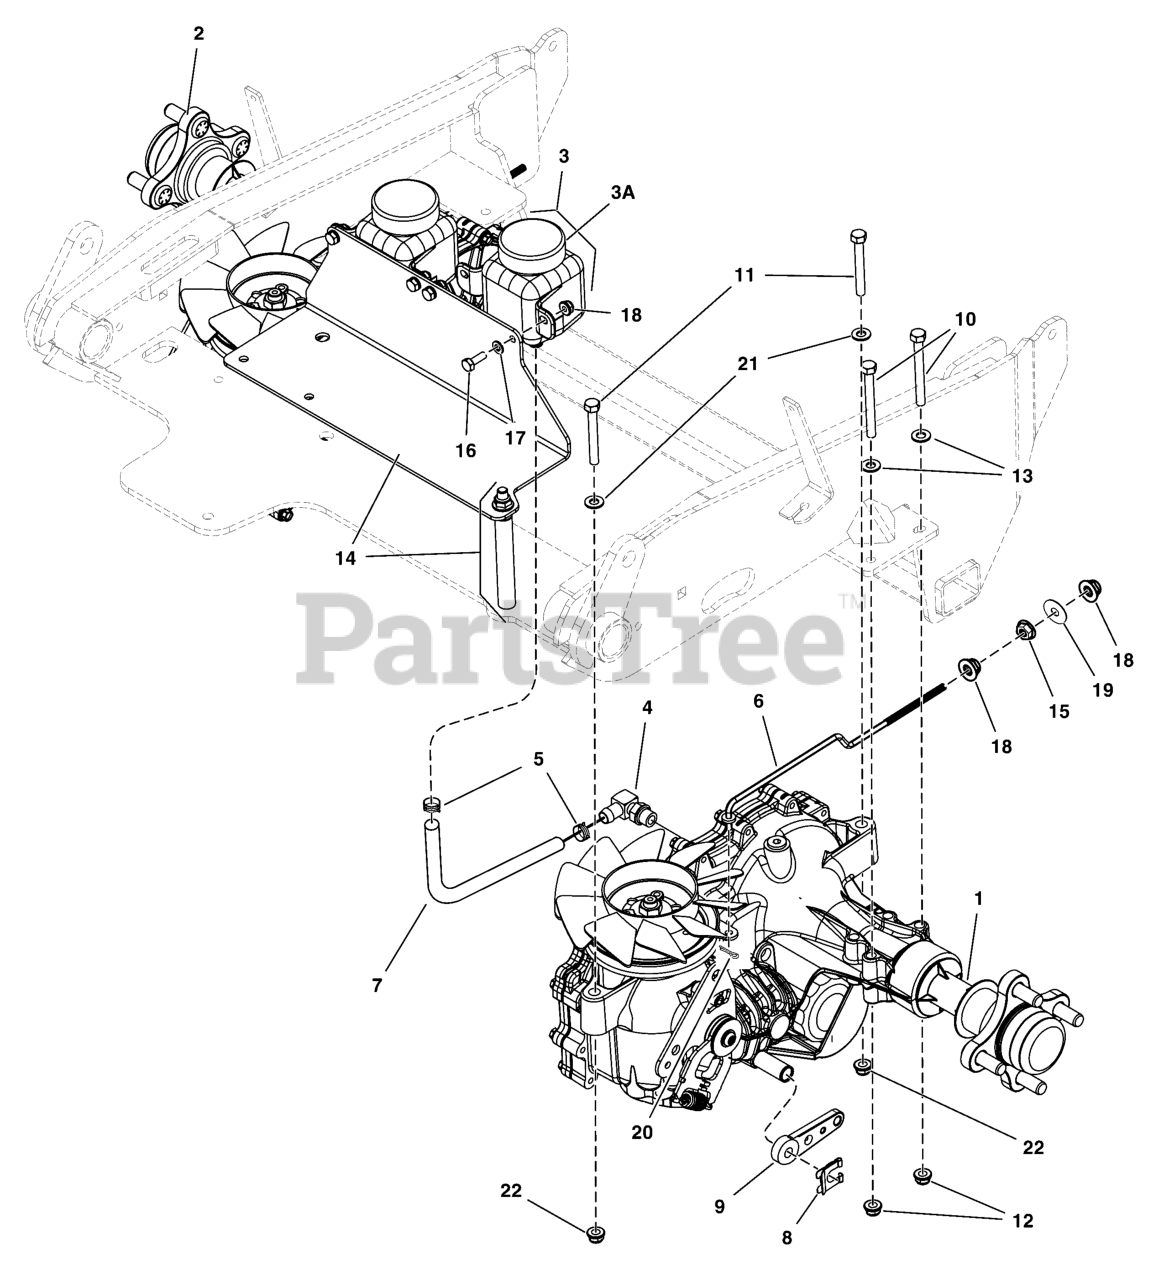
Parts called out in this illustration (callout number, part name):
1	TRANS, 3400, LH, ZS-KHEF-8T7C-11RX
2	TRANS, 3400, RH, ZS-KHEF-8T7C-11RX
3	RESERVOIR, Hydro
3A	RESERVIOR CAP (SV)
4	FITTING, 9/16 O-Ring, 1/2" HOSE, 90 DEG
5	CLAMP, HOSE
6	ROD, DUMP VALVE, IS600, CZ
8	E-CLIP, Brake Arm
10	CAPSCREW, Hex Head, 5/16-18 x 3
11	CAPSCREW, Hex Head, 3/8-16 X 2 1/2
12	NUT, Hex Flange, Nylock, 3/8-16
13	WASHER, .406
14	See Pump Drive Group
15	NUT, Serrated, Flange, 1/4-20, GR5
16	CAPSCREW, Hex Head, 1/4-20 x 3/4 (stiffener to top of cover)
17	WASHER, Flat, 1/4
18	NUT, Flange Nylock , 1/4-20
19	WASHER, 1/4
21	WASHER, .406
22	NUT, Hex Flange, Nylock, 3/8-16
